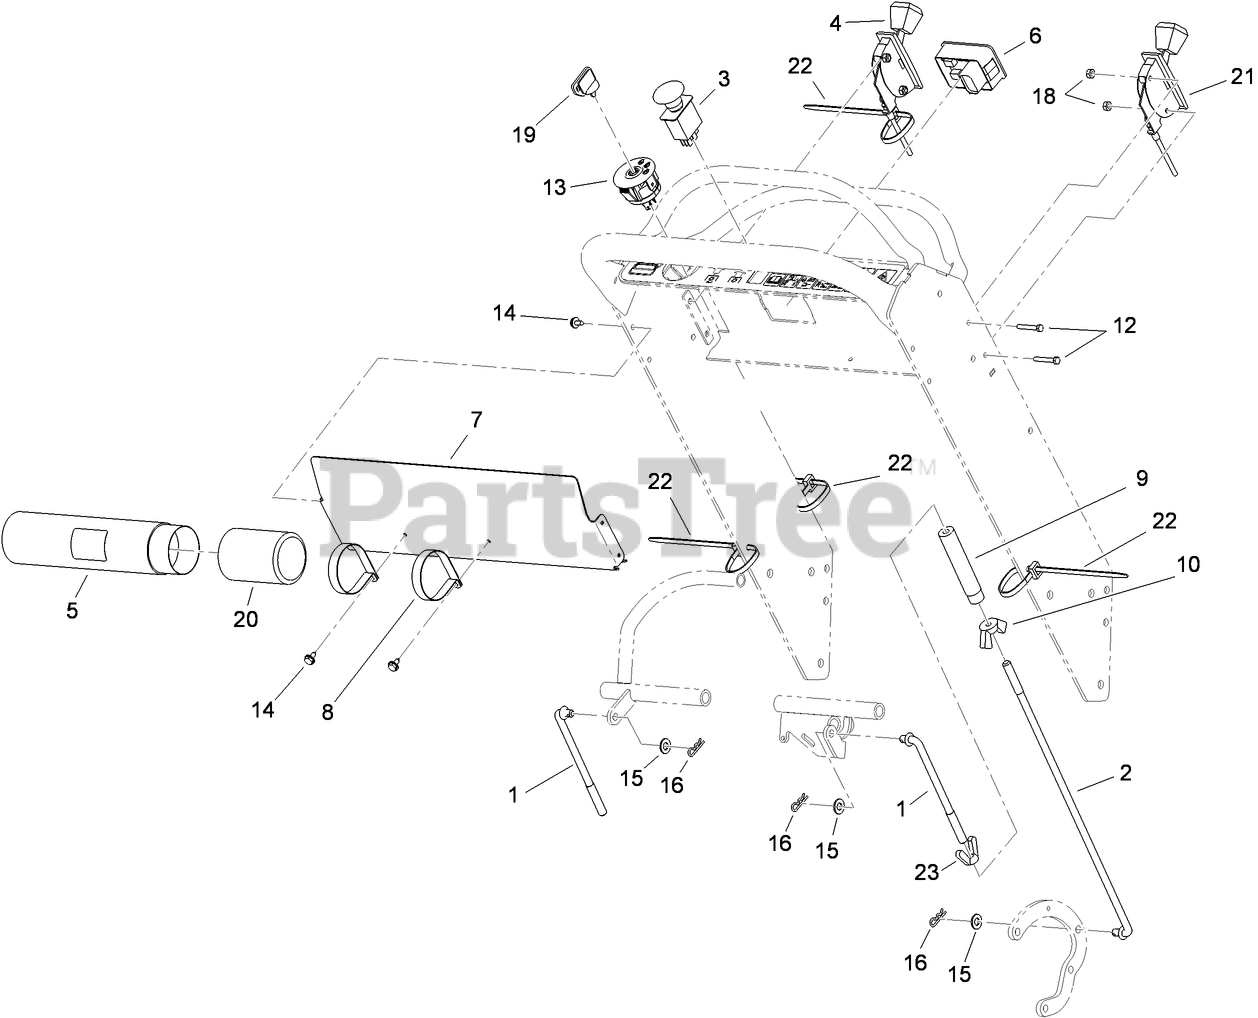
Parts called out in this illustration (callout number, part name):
1	ROD-CONTROL, UPPER
2	ROD-CONTROL, LOWER
3	SWITCH-PTO, ON-ON-(ON)
4	CABLE-THROTTLE
5	TUBE-MANUAL
6	MODULE-METER, HOUR
7	COVER-PANEL, CONTROL
8	CLAMP-R
9	TURNBUCKLE
10	NUT-WING
12	SCREW-HH
13	SWITCH-IGNITION
14	SCREW-HWHTF
15	WASHER-PLAIN
16	PIN-COTTER
18	NUT-LOCK, NI
19	KEY-IGNITION
20	CAP-HOUSING
21	CABLE-CHOKE
22	TIE-CABLE
23	NUT-WING, LH
